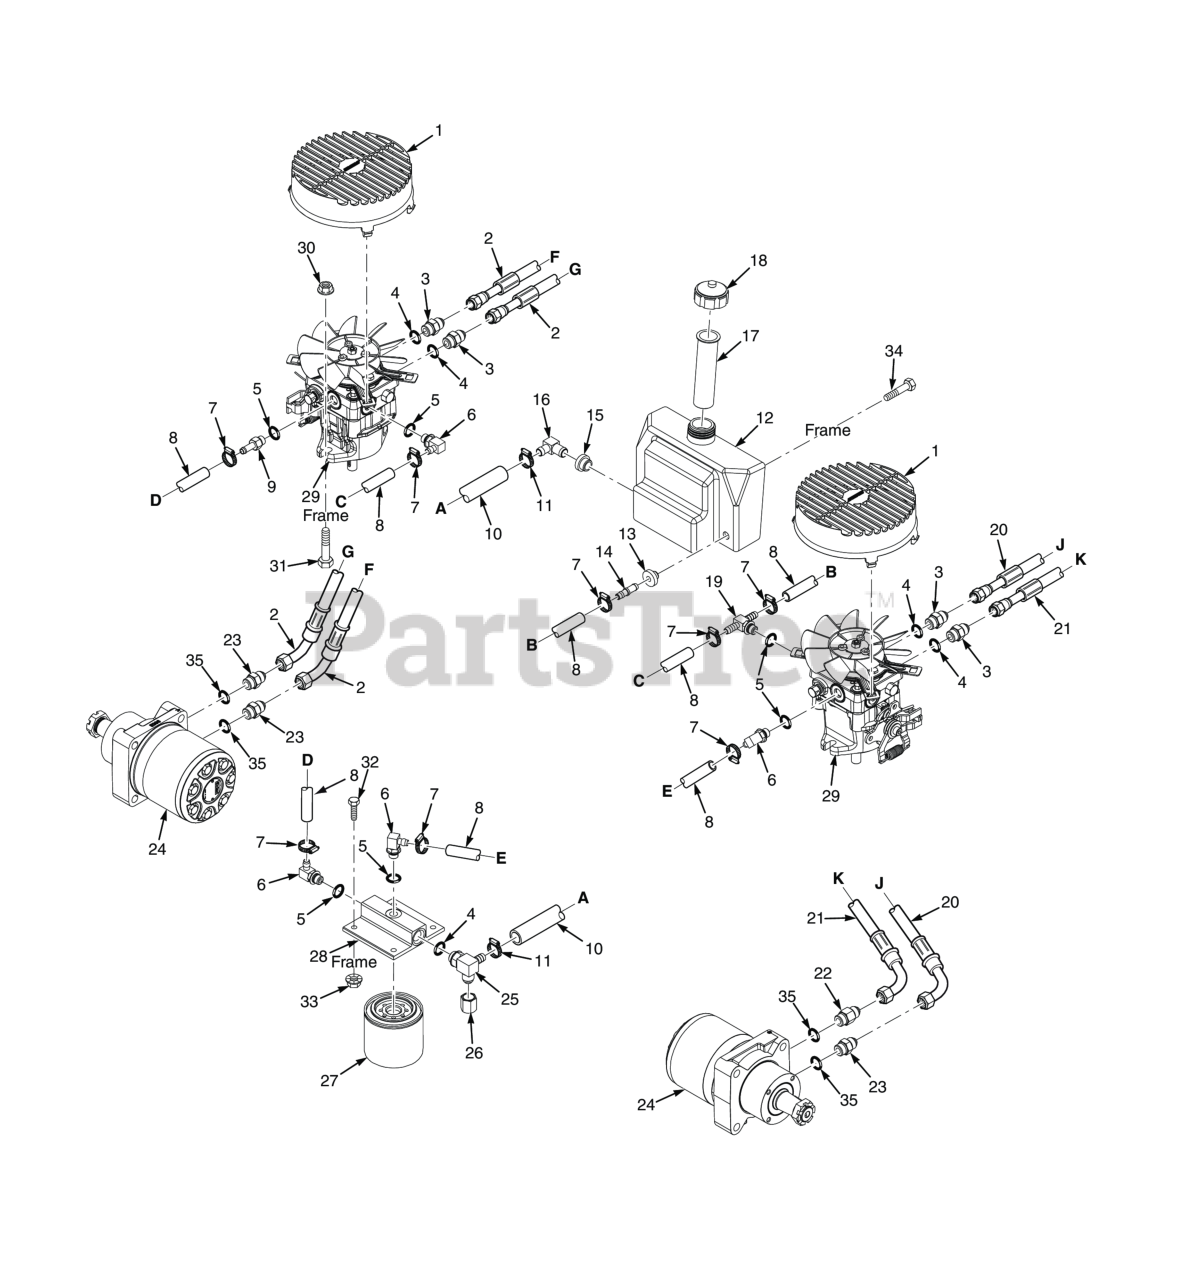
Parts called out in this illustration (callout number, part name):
1	Fan Cover, Pump
2	Hose Assembly
3	Union, 3/4"-16 JIC x 3/4"-16 O-Ring
4	"O" RING, 3/32 X 5/8" ID
5	"O" RING, 5/64 X 15/32 ID
6	Elbow, 90 Degree - 9/16" O-Ring x 3/8" Hose
7	Clamp, .69" Max. / .25" Min. Dia.
8	Hose, 3/8" ID - 10-1/4" Long (Order By The Inch)
9	Fitting, 9/16" O-Ring x 3/8" Hose
10	Hose Assembly, 1/2" ID (Oil Reservoir to Filter Base)
11	Clamp, Cable 3/4" I.D.
12	Hydraulic Tank Assy
13	Bushing, 0.56" Dia. Viton
14	Fitting, Straight
15	Bushing, 0.78" Dia. Viton
16	Fitting, 90 Degree - 1/2" Hose
17	Insert, Filler Neck
18	CAP, HYDRAULIC TANK
19	Tee Fitting, O-Ring to Barb
20	Hose Assembly
21	Hose Assembly
22	Fitting, 1/2" JIC x 5/8" O-Ring (LH Wheel Motor - Upper Port Only)
23	TUBE UNION, 3/4-16 JIC TO 7/8-14 "O" RING
24	Wheel Motor, Parker
25	Tee, 3/4" O-Ring x JIC x 1/2" Hose
26	CAP, 3-4-16 JIC
27	OIL FILTER, SPECIAL
28	Filter Head Assembly
29	Pump, LH (PK-3KCC-GA1F-XXXX)
29	Pump, RH (PK-3HCC-GA1F-XXXX)
30	Nut, Flange Elastic Stop Nut, 3/8-16
31	Bolt, Hex Head, 3/8-16 x 1-1/2"
32	BOLT, SERRATED FLANGE HEX HEAD 5/16-18 X 3/4"
33	Nut, Serrated Flange 5/16-18 (Right Front Engine Mounting, Briggs and Kohler Only)
34	CAP SCREW, 5/16-18 X 1/2" SERRATED FLANGE HEX
35	"O" RING, 3/32 X 3/4 ID
